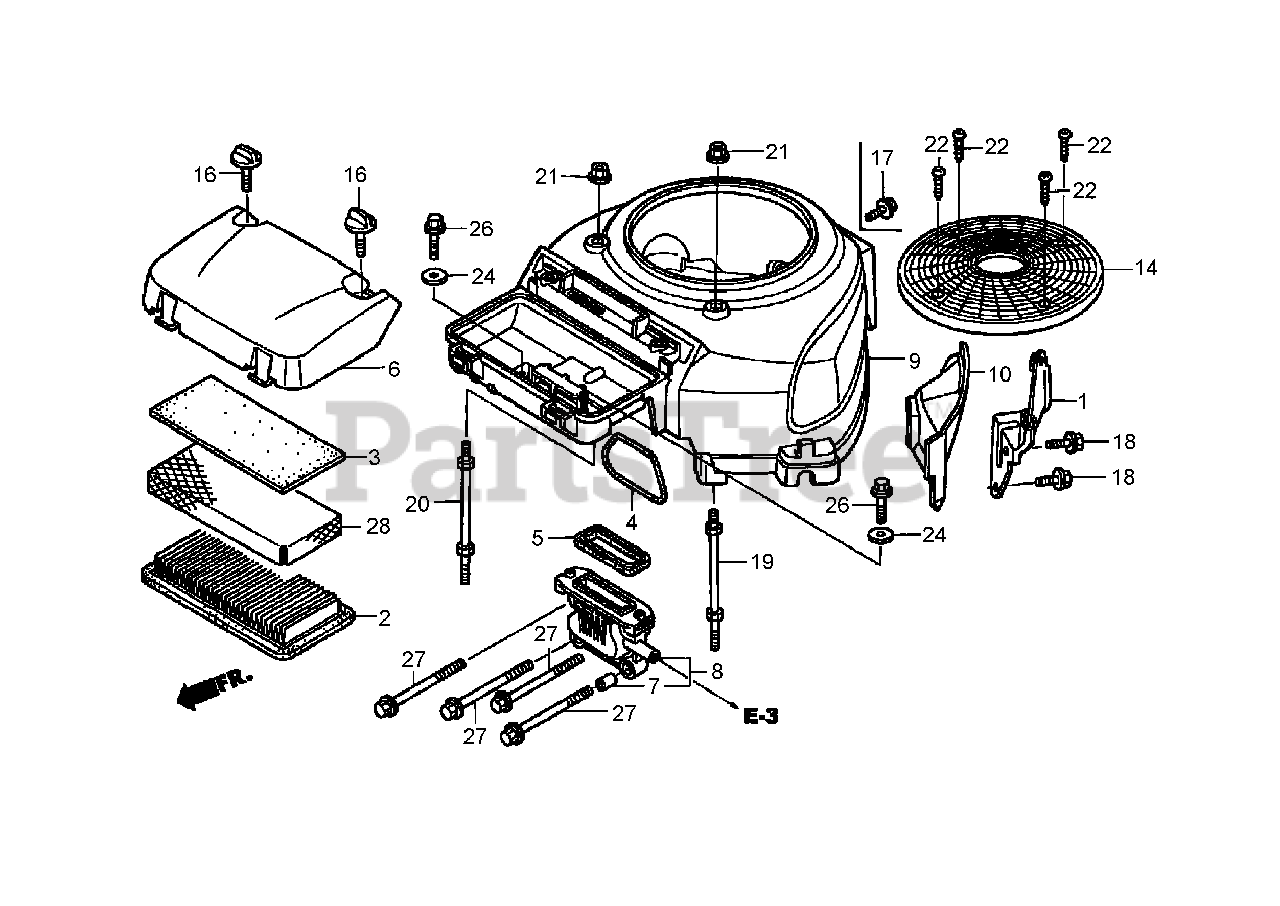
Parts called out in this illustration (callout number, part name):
1	STAY-PUMP, FUEL
2	ELEMENT-CLEANER, AIR
3	FILTER (OUTER)
4	GASKET-CLEANER, AIR
5	SEAL-HOUSING, AIR CLEANER
6	COVER-CLEANER, AIR
7	COLLAR A-CLEANER, AIR
8	ELBOW-CLEANER, AIR
9	COVER-FAN (NH1) (BLACK)
10	PLATE-SIDE
14	GRID-SCREEN NH105 (MATTE BLACK)
16	BOLT (6MM)
17	BOLT-FLANGE (6X14) (CT200)
18	BOLT-FLANGE (6X14) (C T200)
19	BOLT-STUD, LEFT (IGNITION COIL)
20	BOLT-STUD, RIGHT (IGNITION COIL)
21	NUT-FLANGE (6MM)
22	SCREW-TAPPING (4X16)
22	SCREW-TAPPING (4X30) (P0)
24	WASHER-PLAIN (6MM)
26	BOLT-FLANGE (6X12)
27	BOLT-FLANGE (6X100)
28	GRID-CLEANER, AIR
